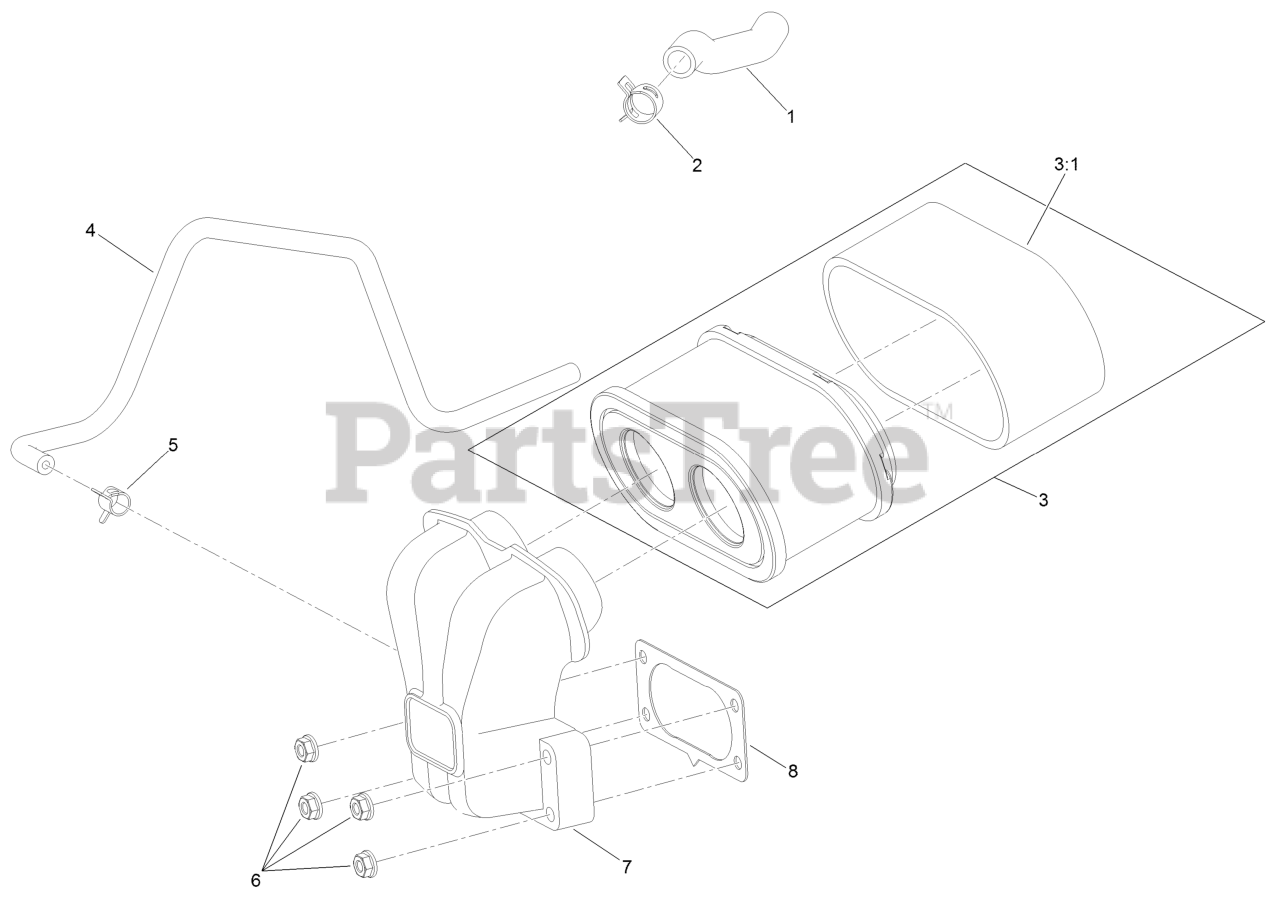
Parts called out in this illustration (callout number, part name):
1	Tube-Breather
2	Clamp-Hose
3	Filter-Air, Complete
3:1	Filter-Pre, Foam
4	Hose-Fuel
5	Clamp-Hose
6	Nut-Flange
7	Manifold-Filter, Air
8	Gasket-Carburetor
